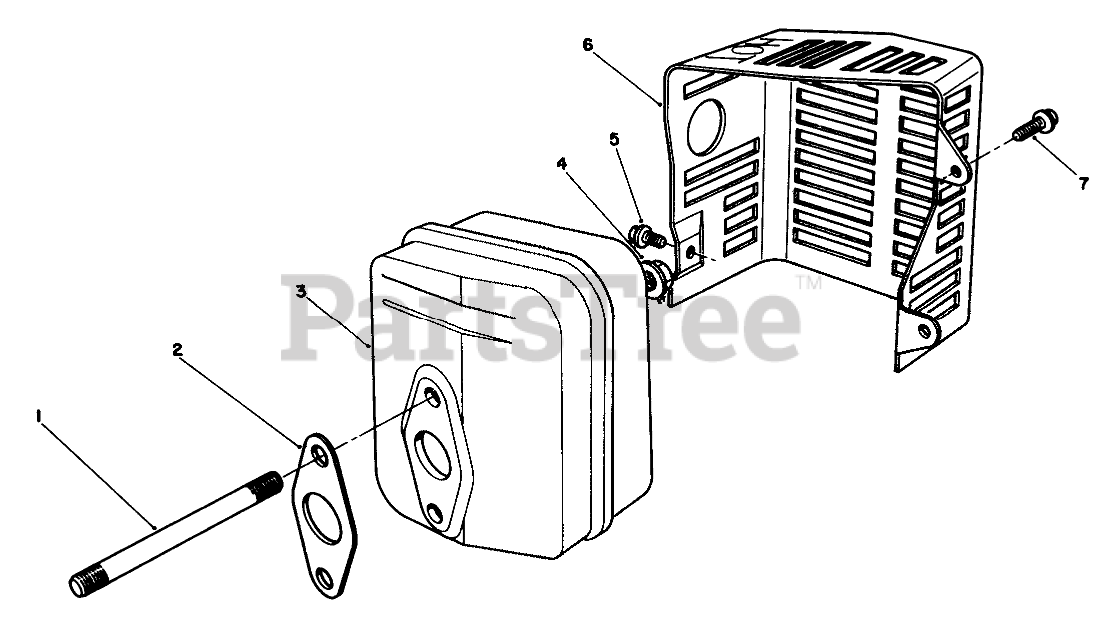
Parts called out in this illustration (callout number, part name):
2	GASKET
3	MUFFLER
5	SCREW
6	COVER
